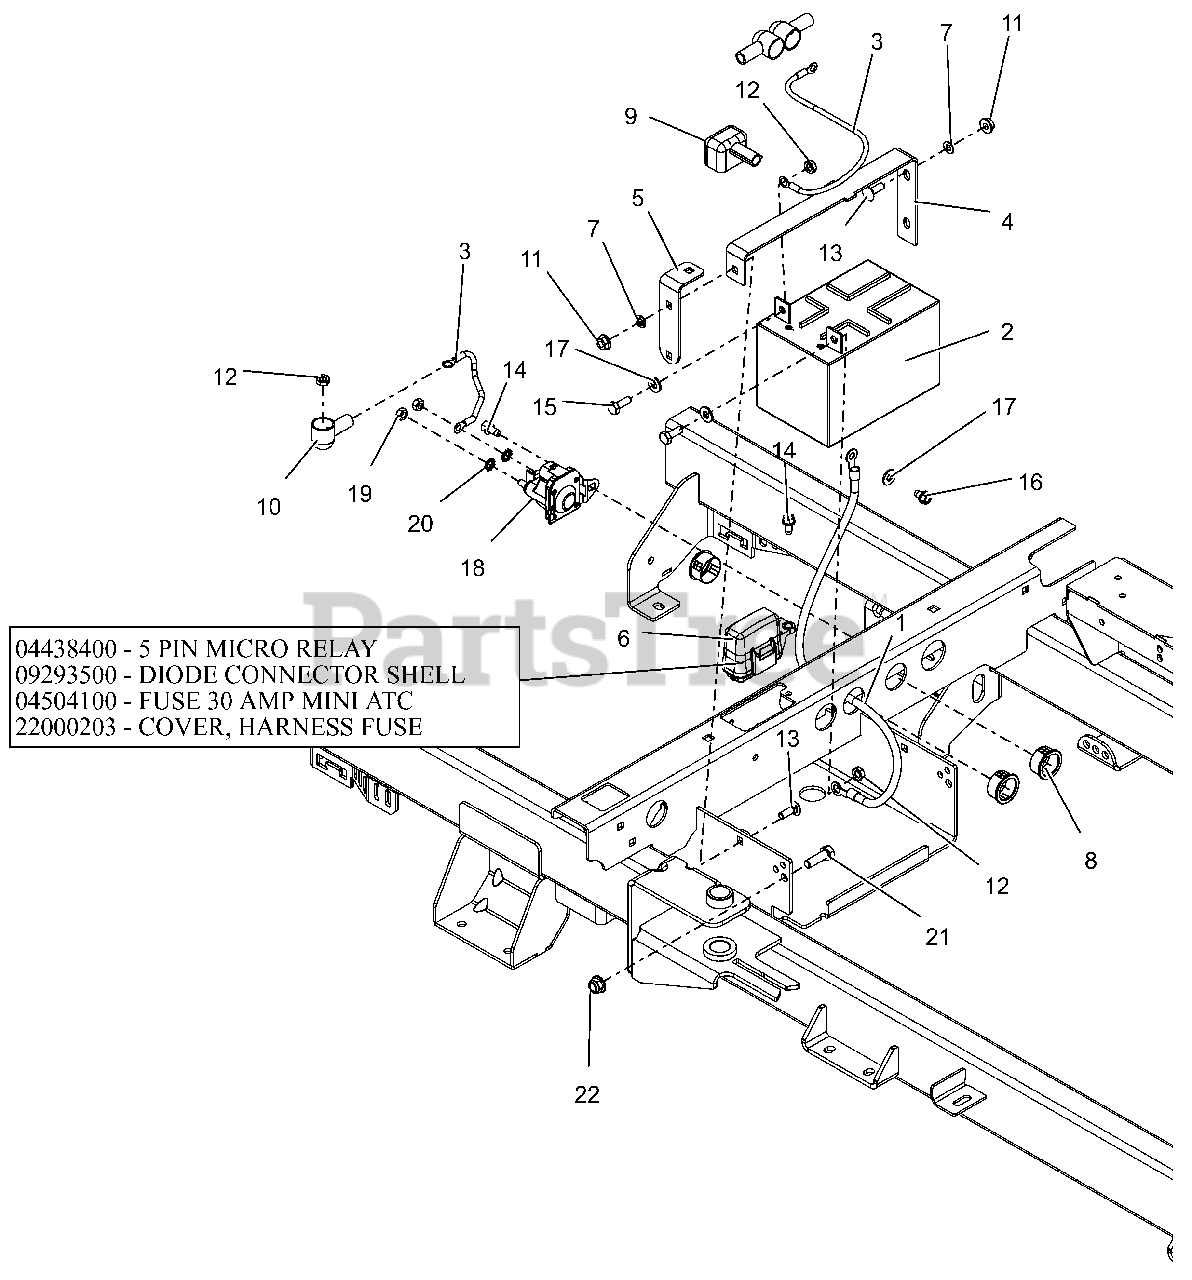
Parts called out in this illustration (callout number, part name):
1	CABLE-NEGATIVE BATTERY 24.00"
2	BATTERY, 12V 12A-190CCA
3	CABLE,POS W/2 1/4 RING 15.0 LG
4	BRKT, BATTERY HOLD-DOWN
5	BRKT, BATTERY HOLD DOWN
6	HARNESS, WIRE-4POS KEY IKON/ZT
6	RELAY,MICRO5 TERML W/RESISTOR
6	DIODE, CONNECTOR SHELL
6	FUSE,30 AMP MINI-ATC
6	COVER, FUSE
7	NUT-PUSH .25X.50 O.D.
8	BSHG, PANEL SNAP .937X1.11X.56
9	INSULATOR
10	BOOT, EYELET TERMINAL
11	NUT-LK-TOP-FLG .250-20 GF ZCC
12	NUT-KEPS .250-20 ZCC
13	BLT, RHSN .25-20X.750 G5 ZCC
14	SCR-TAP .25-20X.50 HWH ZCC
15	BLT, HEX .25-20X.75 G5 ZCC
16	SCR,TAP .25-20X.375 HWH TR ZCC
17	WSHR,FLT .281X.625X.065 ZCC
18	SOLENOID, STARTER (SEALED)
19	NUT-STD M6-1.0 ZCC
20	WSHR,LK-EXT.262X.502X.026 ZCC
21	BLT,HEX .31-18X1.00 G5 ZCC
22	NUT,NYL-FLG .31-18 GF ZCC
